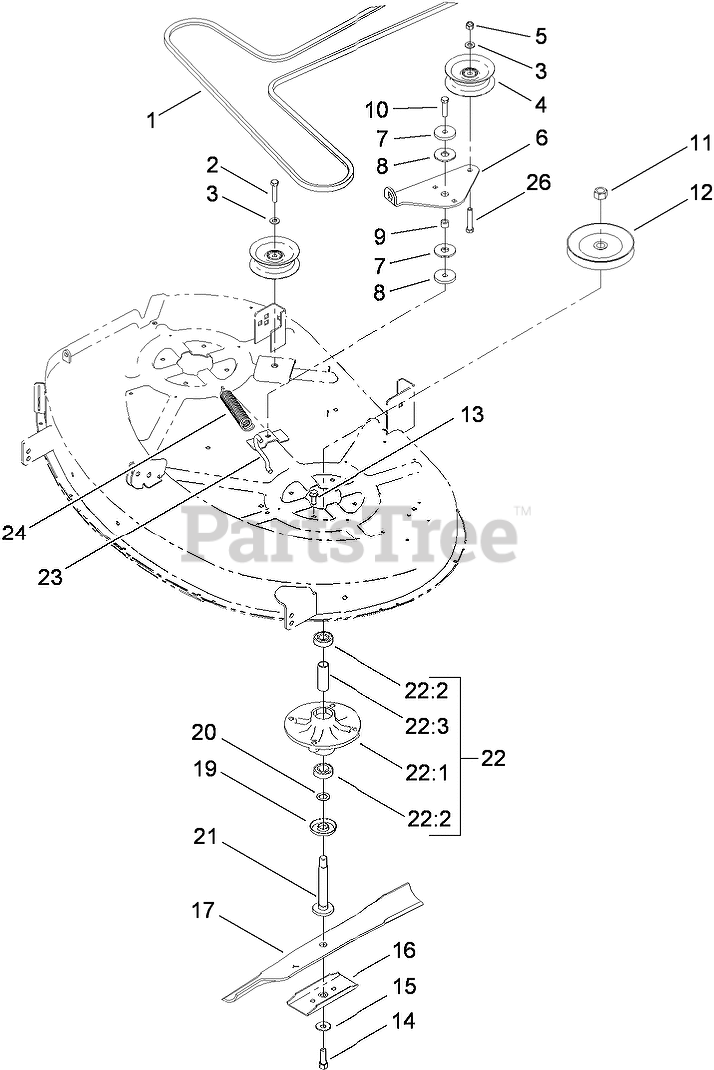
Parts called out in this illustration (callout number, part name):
1	V-BELT
2	SCREW-HH
3	WASHER-FLAT
4	PULLEY-IDLER, FLAT
5	NUT-LOCK, NI
6	ARM-IDLER
7	WASHER-PLAIN
8	WASHER-FRICTION, COMPOSITE
9	SPACER
10	SCREW-HH
11	NUT-HEX
12	PULLEY
13	SCREW-TAPTITE
14	SCREW-HH
15	WASHER-BELLEVILLE
16	STIFFENER-BLADE
17	BLADE-21.6 INCH
19	SHIELD-BEARING
20	SPACER
21	SHAFT-SPINDLE
22	SPINDLE ASM
22:1	HOUSING-SPINDLE
22:2	BEARING-BALL
22:3	SPACER
23	HOOK-RETURN, SPRING
24	SPRING-EXTENSION
26	SCREW-HH
